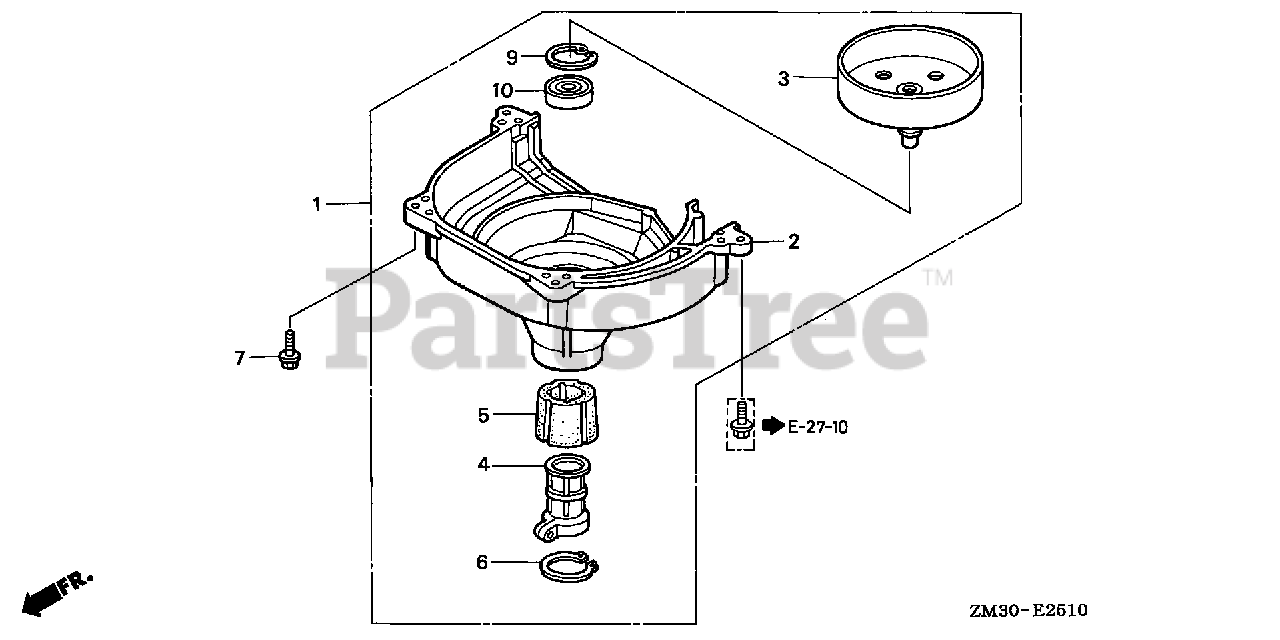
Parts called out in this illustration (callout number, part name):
1	COVER ASSY., FAN *NH35M* (CLOUD SILVER METALLIC)
2	COVER, FAN *NH35M* (CLOUD SILVER METALLIC)
3	CLUTCH OUTER
4	BRACKET, ENGINE MOUNTING
5	RUBBER, ENGINE MOUNTING
6	CIRCLIP (INNER) (45)
7	BOLT, FLANGE (5X18)
9	CIRCLIP, INNER (35MM)
10	BEARING, RADIAL BALL (6202)
